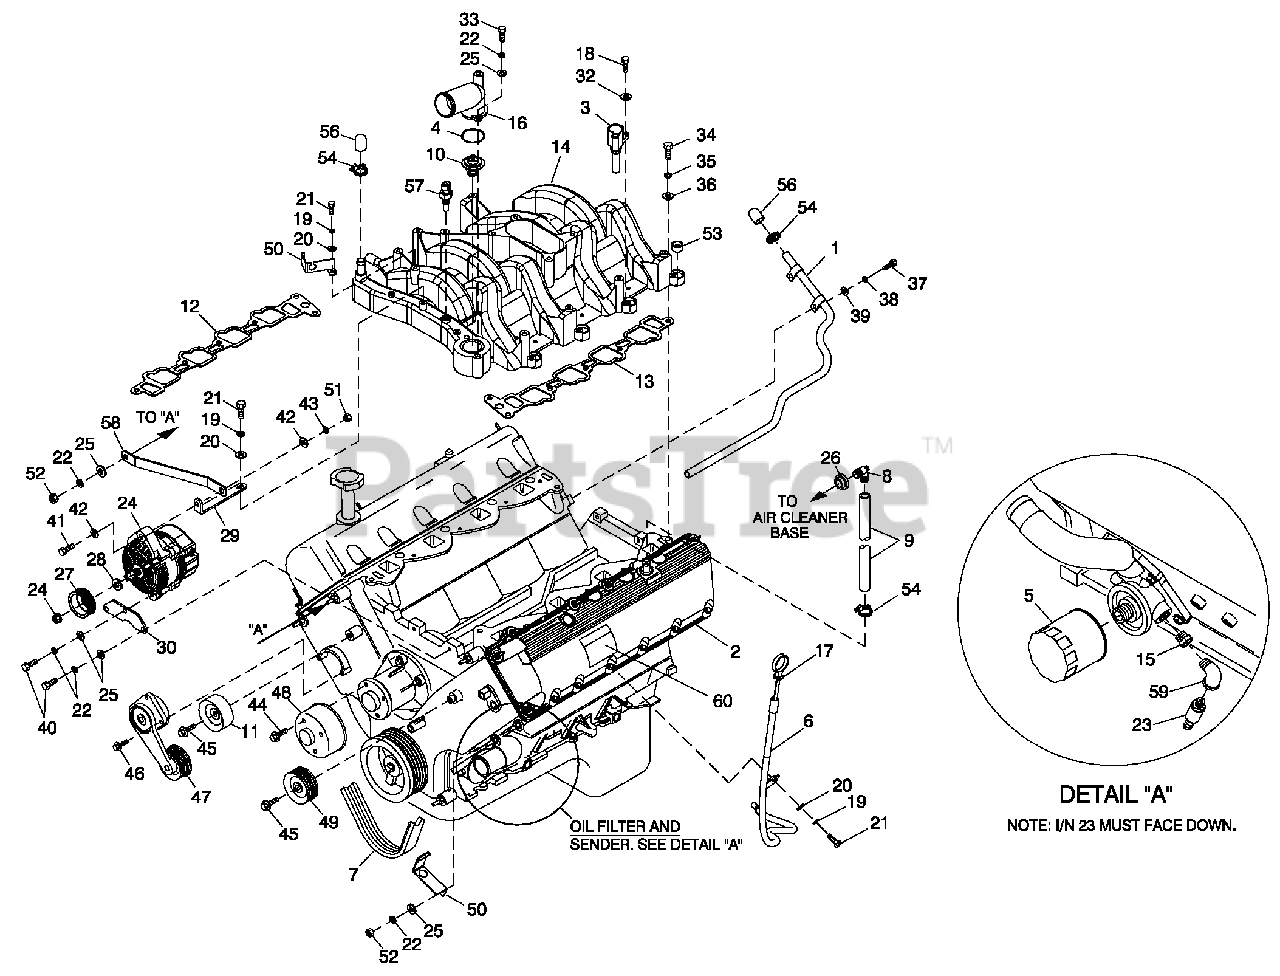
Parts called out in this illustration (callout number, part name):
1	TUBE HEATER WATER
2	ENGNE 5.4L FORD
3	IGNITION COIL ASSY FORD
4	GASKET THERMOSTAT HOUSING FORD
5	OIL FILTER FORD V-10 ENGINE
6	TUBE OIL LEVEL NDICATOR FORD
7	BELT SERPENTINE 65.0" (1800 RPM)
8	BARBED EL 90 3/4 PLASTIC
9	HOSE 3/4 ID SAE-30R2(16.75" LG)
10	THERMOST AT ASSY FORD
11	PULLEY FAN BELT FORD
12	GASKET INTAKE MANIFOLD RIGHT
13	GASKET INTAKE MANIFOLD LEFT
14	INTAKE MANFOLD 5.4L (PLASTIC)
15	BUSHING REDUCER 3/8 TO 1/8 GAL
16	CONNECTION WATER OUTLET FORD
17	REWORK DIPSTICK 5.4L 27.75"
18	SCREW HHC M5-0.8X 25 G8.8
19	WASHER LOCK M6-1/4
20	WASHERFLAT 1/4 ZINC
21	SCREW HHC M6-1.0X 20 G8.8
22	WASHERLOCK M8-5M6
23	SENDEROL PRESSURE 1/8" NPT
24	ALTERNATOR DC W/OUT PULLEY
25	WASHERFLAT 5/16 ZINC
26	GROMMET
27	PULLEY 80 OD DC ALTERNATOR (1800RPM)
28	SPACERDC ALTERNATOR PULLEY
29	BRKT DC ALTERNATOR UPPER
30	BRKT DC ALTERNATOR LOWER
32	WASHERFLAT M5
33	SCREW HHC M8-1.25X90 G8.8
34	SCREW HHC M8-1.25X50 G8.8
35	WASHERLOCK M8-5/16
36	WASHERFLAT 5/16-M8 ZINC
37	SCREW HHC M10-1.5X20 G8.8
38	WASHERLOCK M10
39	WASHERFLAT 3/8-M10 ZINC
40	SCREW HHC M8-1.25X20 G8.8
41	SCREW HHC M10-1.5X45 G8.8 FT
42	WASHERFLAT 3/8-M10 ZINC
43	WASHERLOCK M10
44	SCREW WP PULLEY M8-1.25 X 19
45	BOLT HEX FL HD M8-1.25 X 28
46	BOLT HEX FL HD M8-1.25 X 31
47	TENSIONERENG. AUTOMATIC BELT
48	PULLEY WATER PUMP FORD (1800RPM)
49	PULLEY GROOVED ENGINE IDLER
50	BRACKET SIGNAL CONDITIONER
51	NUT HEX M10-1.5G8 YEL CHR
52	NUT HEX M8-1.25G8 YEL CHR
53	PLUG EXPANSION 14 OD
54	CLAMP HOSE#10.56-1.06
57	TEMPERATURESENDER, DELPHI
58	BRACKET DC ALT STABILIZER
59	ELBOW 90D STREET 1/8
60	DECAL EPA STATIONARY EMERGENCY
